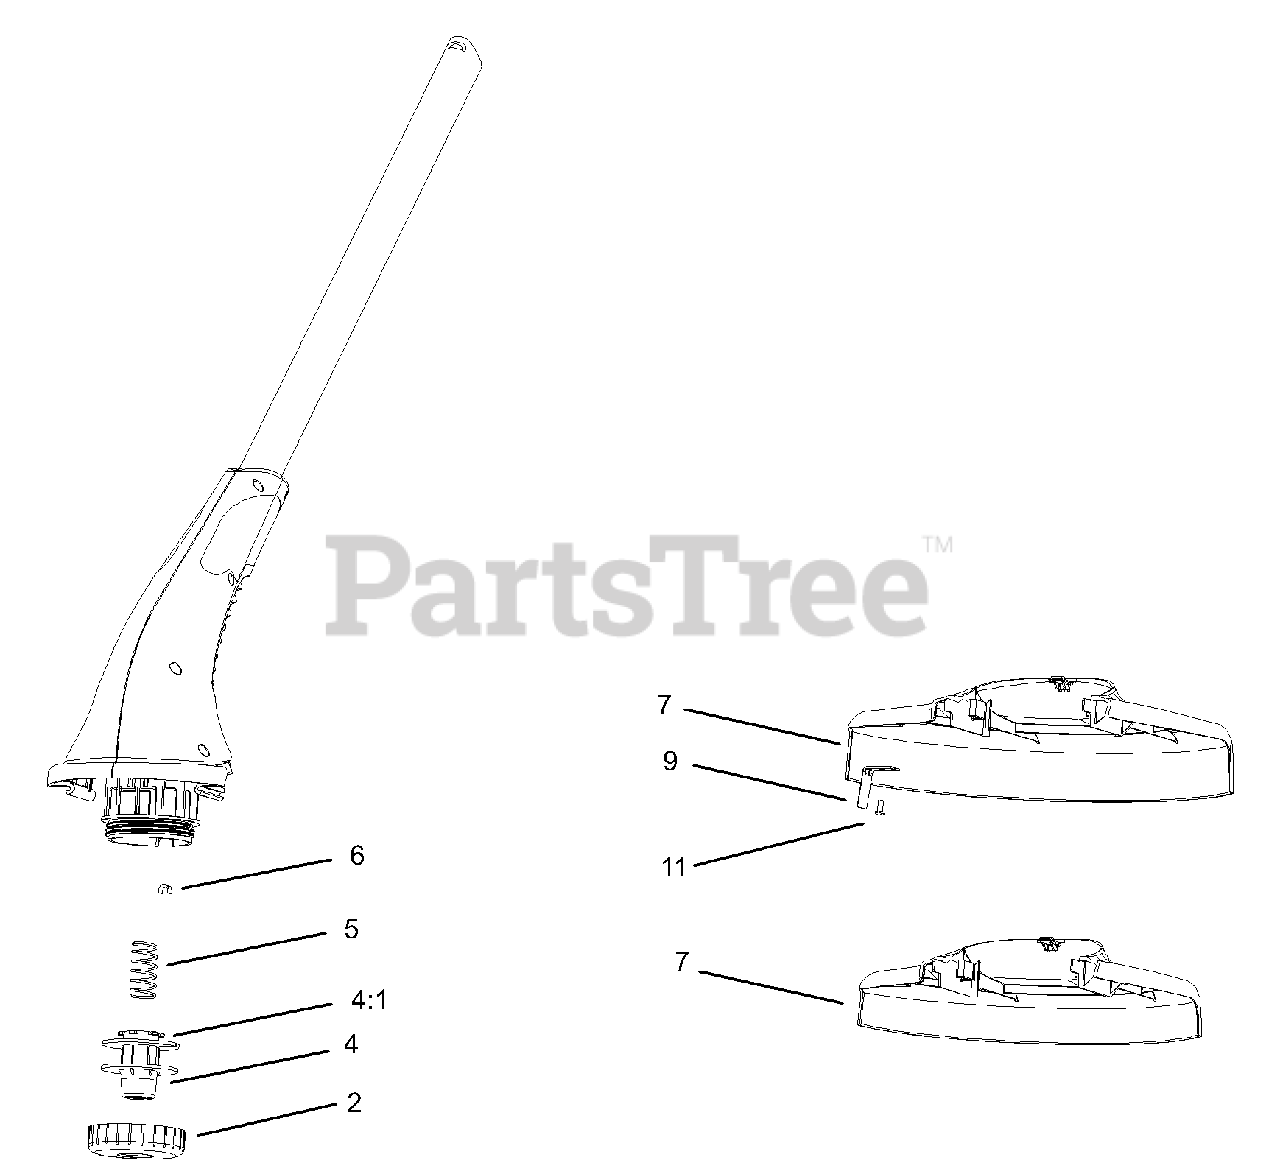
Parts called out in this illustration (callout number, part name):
4	.065 SPOOL ASM
4:1	SPOOL-LARGE
5	Spring-Extension
6	Eyelet-Drum
7	Shield-11in (only on: 51354)
7	Shield-12in (only on: 51355, 51356)
9	Blade-Cutoff
11	Screw-Pan Hd
